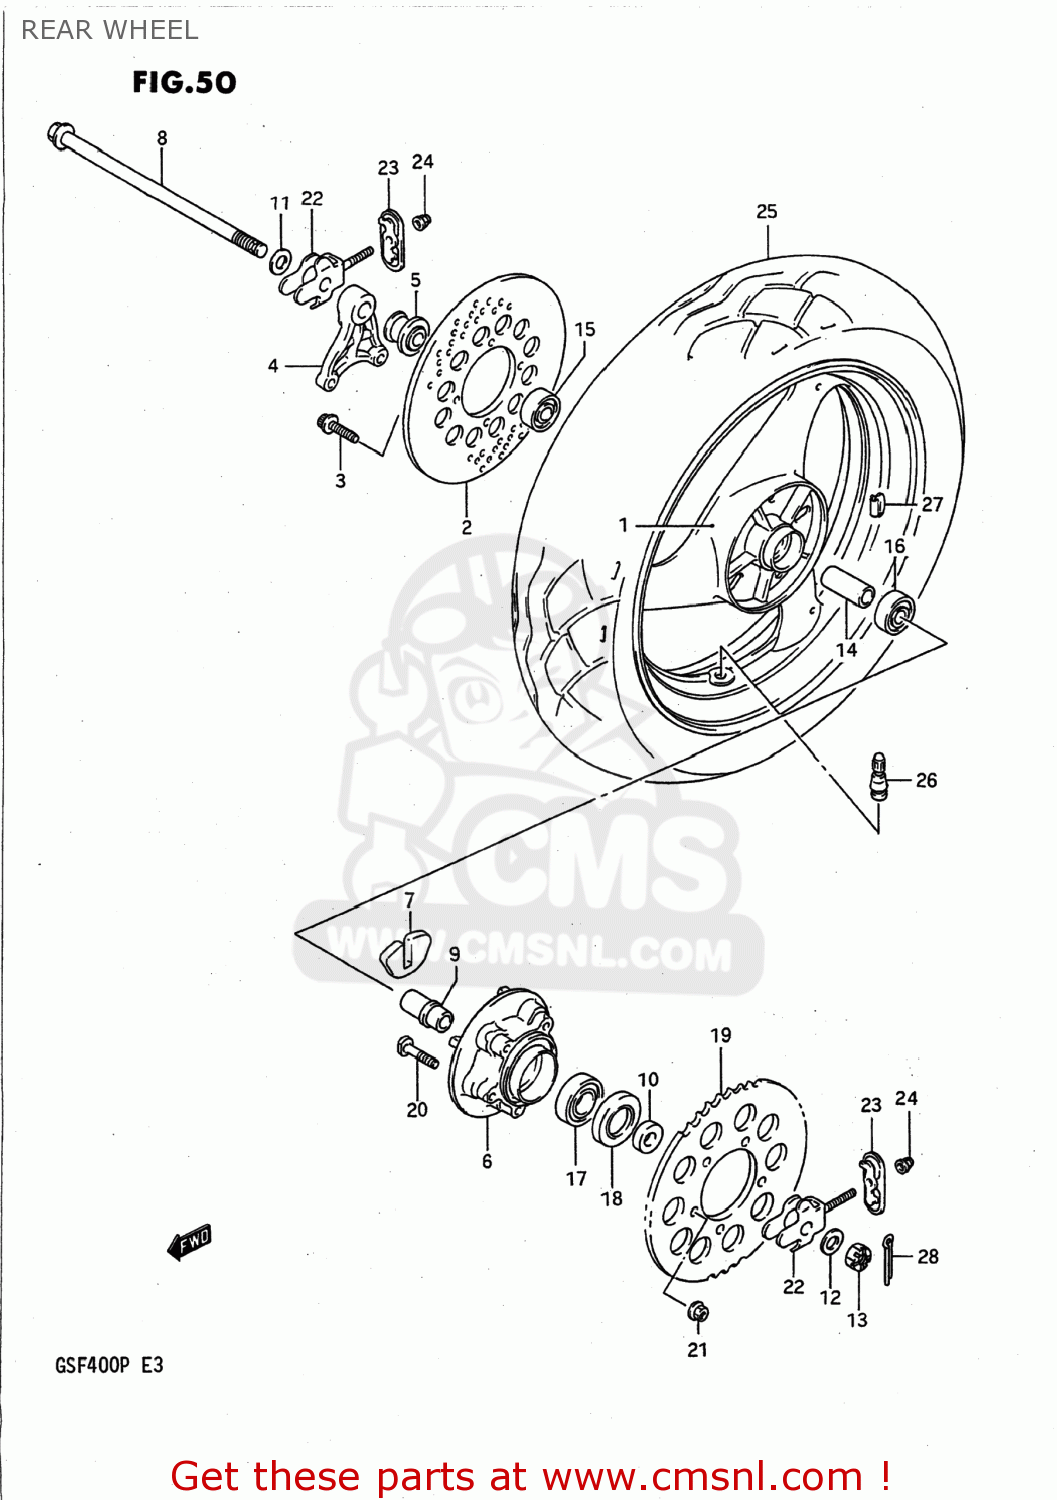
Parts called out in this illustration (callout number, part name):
1	WHEEL,REAR
2	DISC,RR BRAKE
3	BOLT
4	BRACKET,RR,CALIPER
5	SPACER,RR AXLE,R
6	DRUM,RR SPROCKET MOUNTING
7	ABSORBER,RR HUB SHOCK
8	AXLE,REAR
9	RETAINER,RR SPROCKET DRUM
10	SPACER,RR AXLE,L
11	WASHER
12	WASHER(17X34X3)
13	NUT
14	SPACER(17.5X25X78)
15	BEARING
16	BEARING
17	BEARING(25X62X17)
18	SEAL,OIL(35X62X8)
19	SPROCKET,REAR
20	BOLT
21	NUT
22	ADJUSTER,CHAIN
23	PLATE,CHAIN ADJUSTER
24	NUT
25	TIRE,RR(150/70-17 69H)
26	VALVE ASSY,WHEEL RIM(TR412)
27	BALANCER,WHEEL
28	PIN,COTTER
